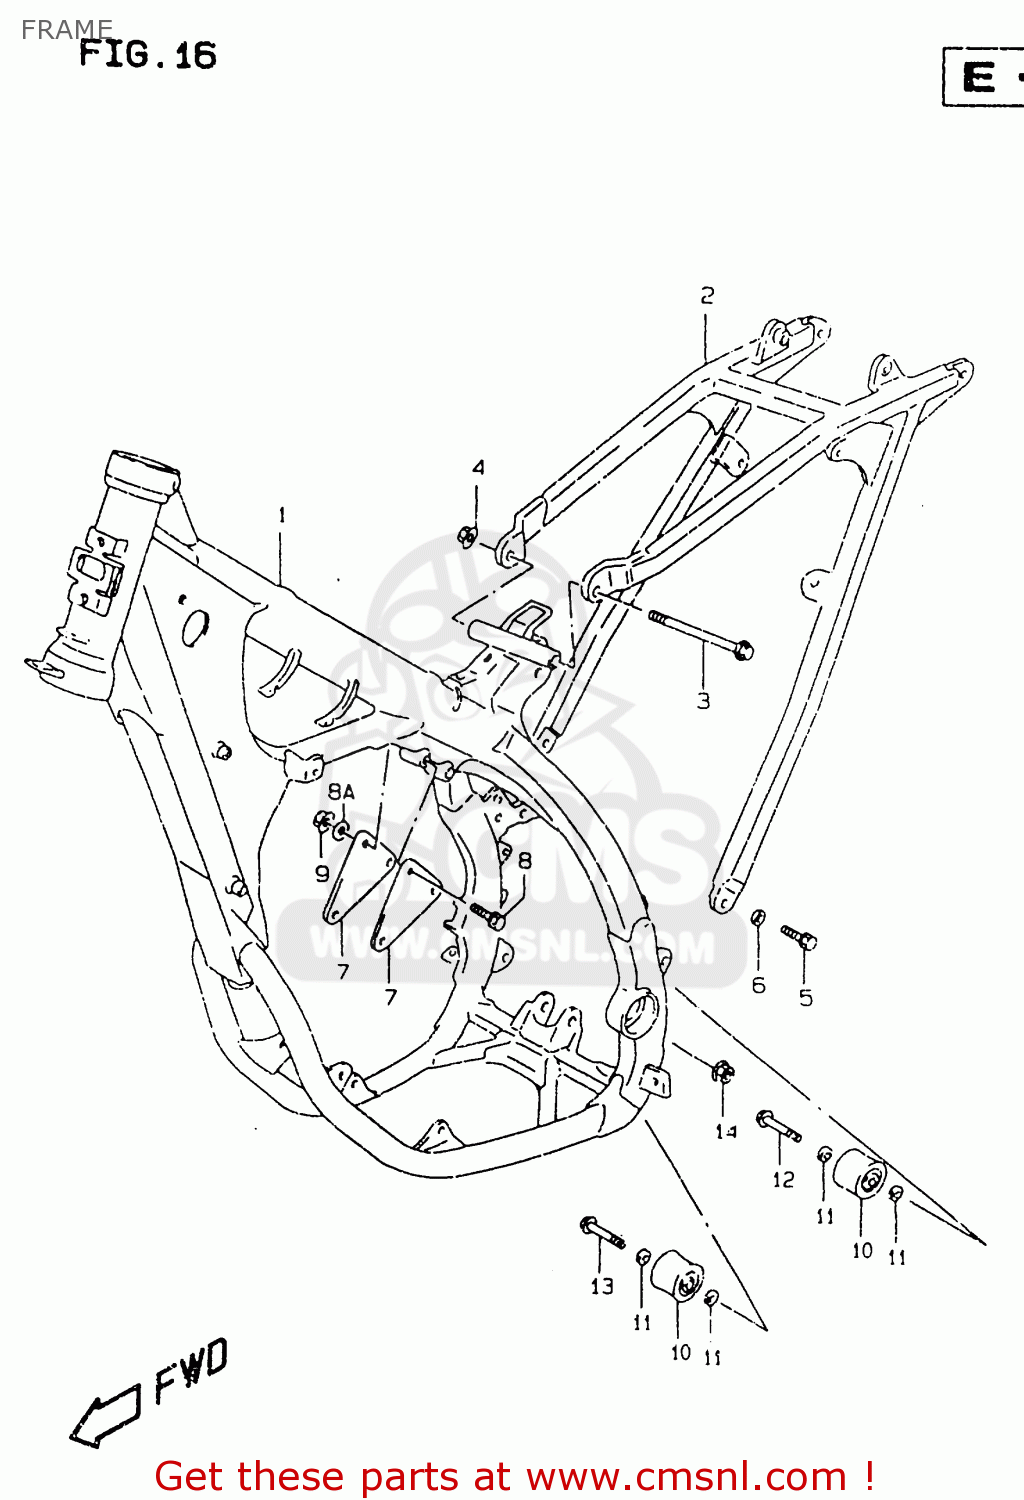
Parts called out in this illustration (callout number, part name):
1	FRAME COMP
2	RAIL,SEAT
3	BOLT(8X120)
4	NUT
5	BOLT 8X16
6	WASHER
7	PLATE,ENG MTG UPR
8	BOLT(8X41)
8A	WASHER
9	NUT
10	ROLLER,CHAIN
11	WASHER
12	BOLT(8X41)
13	BOLT(8X45)
14	NUT
